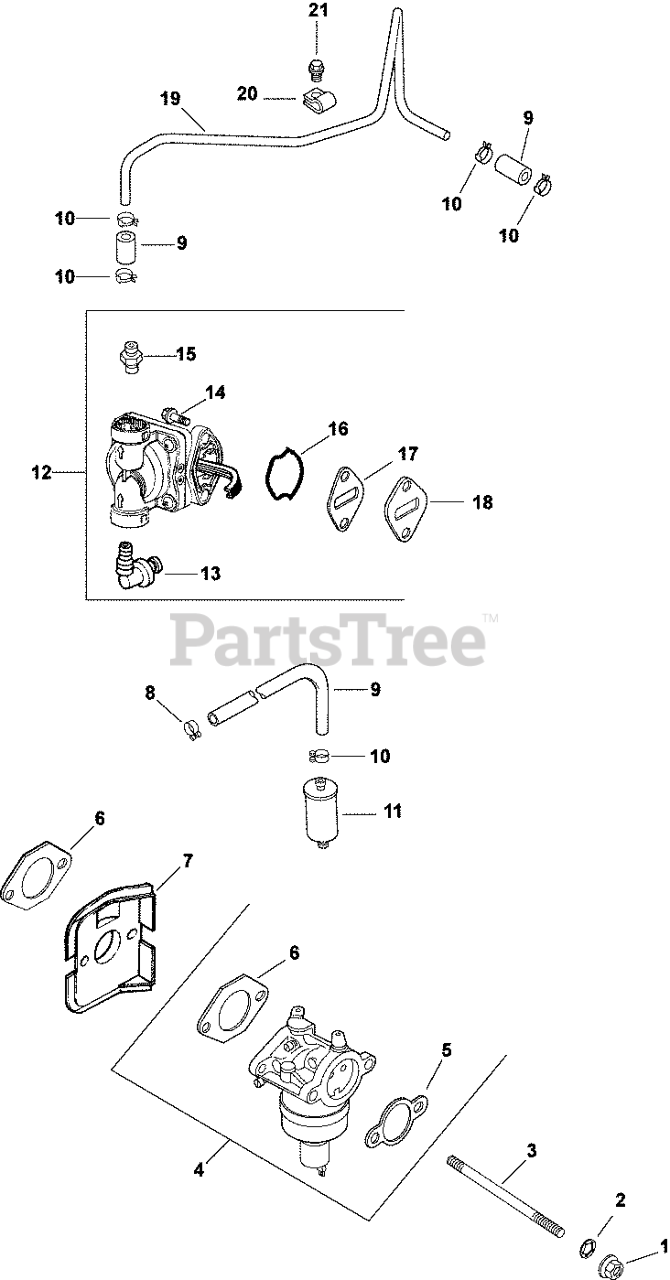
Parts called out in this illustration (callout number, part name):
1	NUT, FLG M6X1.0
2	WASHER, INT TOOTH LOCK 1/4"
3	STUD,M6X1.0X116
4	KIT, CARBURETOR
5	GASKET, AIR CLEANER BASE
6	GASKET, CARBURETOR
7	DEFLECTOR, HEAT
8	CLAMP, BAND SPRING HOSE-(#2523737S)
9	HOSE,LW PERM.FUEL 24.00"-USE 25 111 81-S
10	CLAMP, HOSE (KM)-USE 25 237 31-S
11	FILTR,FUEL 75 MICRON (GRAVTY FEED)
12	KIT, FUEL PUMP
13	CONNECTOR, 90 DEG. HOSE
14	SCREW, LBD SKT M6x1.0x20-(#25086403S)
15	KIT, STRAIGHT FITTING
16	O-RING, FUEL PUMP
17	GASKET, FUEL PUMP
18	SPACER, FUEL PUMP
19	LINE, FUEL
20	CLIP, TUBE & WIRING (KM)
21	SCREW, FLG THD FRM M5X.8X10
